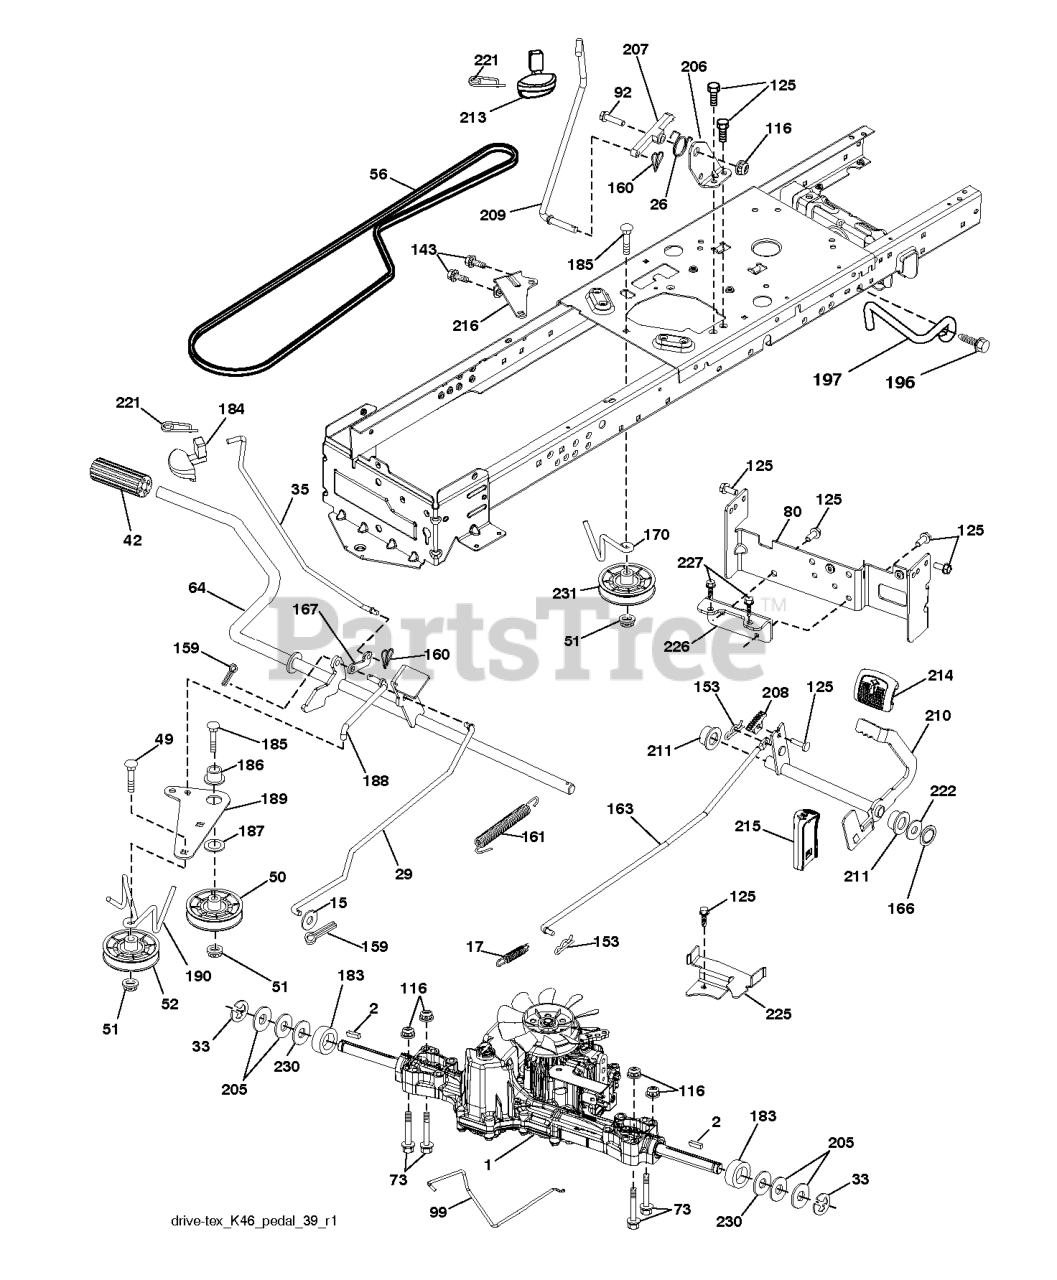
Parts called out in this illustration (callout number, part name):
2	SQUARE KEY
15	WASHER
17	SPRING.BRAKE.K46.GREEN
26	SPRING.RETURN.CRUISE
29	ROD.BRAKE.K46
35	ROD .BRAKE. PARKING. GT. HUSQ.
42	PEDAL COVER T
50	IDLER.FLAT.910.OFFSET
51	NUT LOCK FLG 3/8-16 UNC
52	IDLER.V-GROOVE.910.OFFSET
56	V-BELT.MOWER.92.40.42/K46
64	SHAFT.ASM.PEDAL.BRK.CNTR
80	STRAP.TORQUE.K46.K57R.TT
92	BOLT
99	ROD.SPRING.BYPASS.K46.LT.Z
116	NUT LOCK HEX FLANGE 5/16-18
125	SCREW
143	Screw 5/16-18 x 1/2 Hex, Self Tapping 5/16-18 x 1/2
153	RETAINER M
159	COTTER PIN
160	RETAINER CLIP
161	SPRING, RETURN LT
163	ROD.CONTROL.K57R.K46
166	NUT.PUSH.625
167	LATCH.BRAKE.SPRING
170	KEEPER.CENTER SPAN.1.688
183	SPACER AXLE
184	RB HANDLE.PARKG.BRK.HUS/PRED
186	SPACER.RETAINER
187	WASHER 12/32X2X10GA
188	RP.LINK.CLUTCH.GROUND.DRIVE
189	BELLCRANK.GROUND.DRIVE.TEX.
190	KEEPER.BELLCRANK.DRIVE
196	SCREW 3/8-16X1
197	LINK.CLUTCH.ANIT-ROTAT
206	BRKT.MOUNT.LATCH.CRUIS
207	LATCH.CONTROL.CRUISE
208	GEAR.SECTOR.CONTROL.CR
209	ROD.CONTROL.CRUISE.GT.
210	ROCKER.ASM.PEDAL.CONTR
211	BEARING.NYLON
213	KNOB.CONTROL.CRUSIE.HU
214	PEDAL.FORWARD.PAD.TEX
215	PEDAL.REVERSE.TEX.GT.4
216	BRACKET.PULLEY.IDLER.W/TEX
221	RETAINER.SPRING.CLIP.H
222	WASHER 21/32 X 1-1/4 X 10 GA.
225	KEEPER.BELT.TRANSAXLE.K46
226	BRACKET.MOUNT.TORQUE.K46.TLT
227	SCREW.THDROL.5/16-18X3/4.TTY
230	WASHER.HARDENED
231	IDLER.V-GROOVE.1.688.OFFSET
